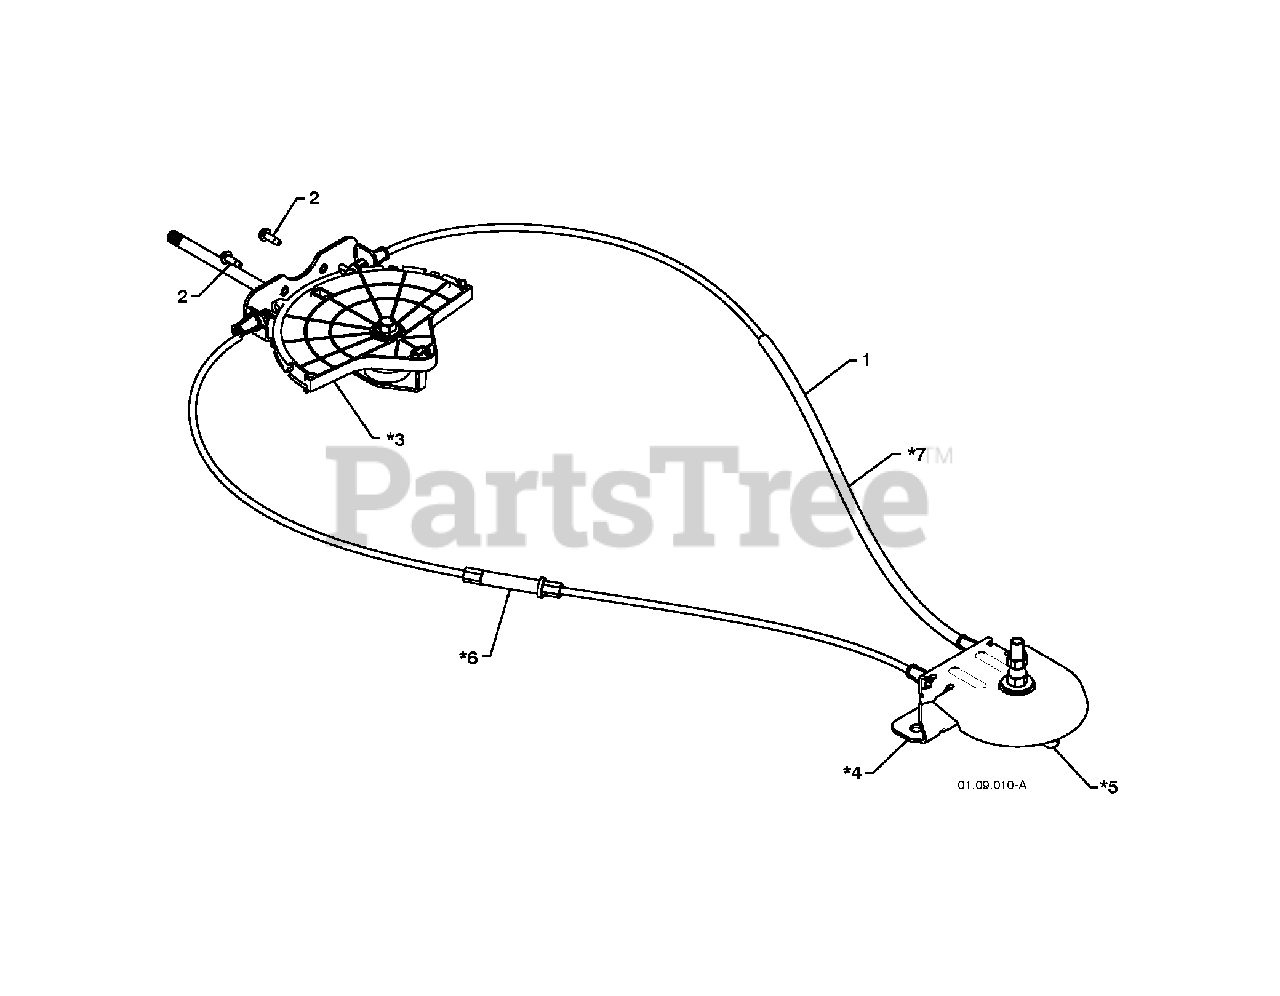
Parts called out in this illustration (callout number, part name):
1	LEVER/CABLE.ASM.ROTATOR
2	SCREW #10-24 X 5/8
3	CHUTE.ROT.HEAD.SERVICE
4	SNOW.PIVOT.BRKT.BLK.SERVICE
5	SNOW.PIVOT.PULLY
6	SNOW.CBL.ASM.ADJ.SERVICE(74)
7	SNOW.CBL.ASM.SERVICE(428272)
